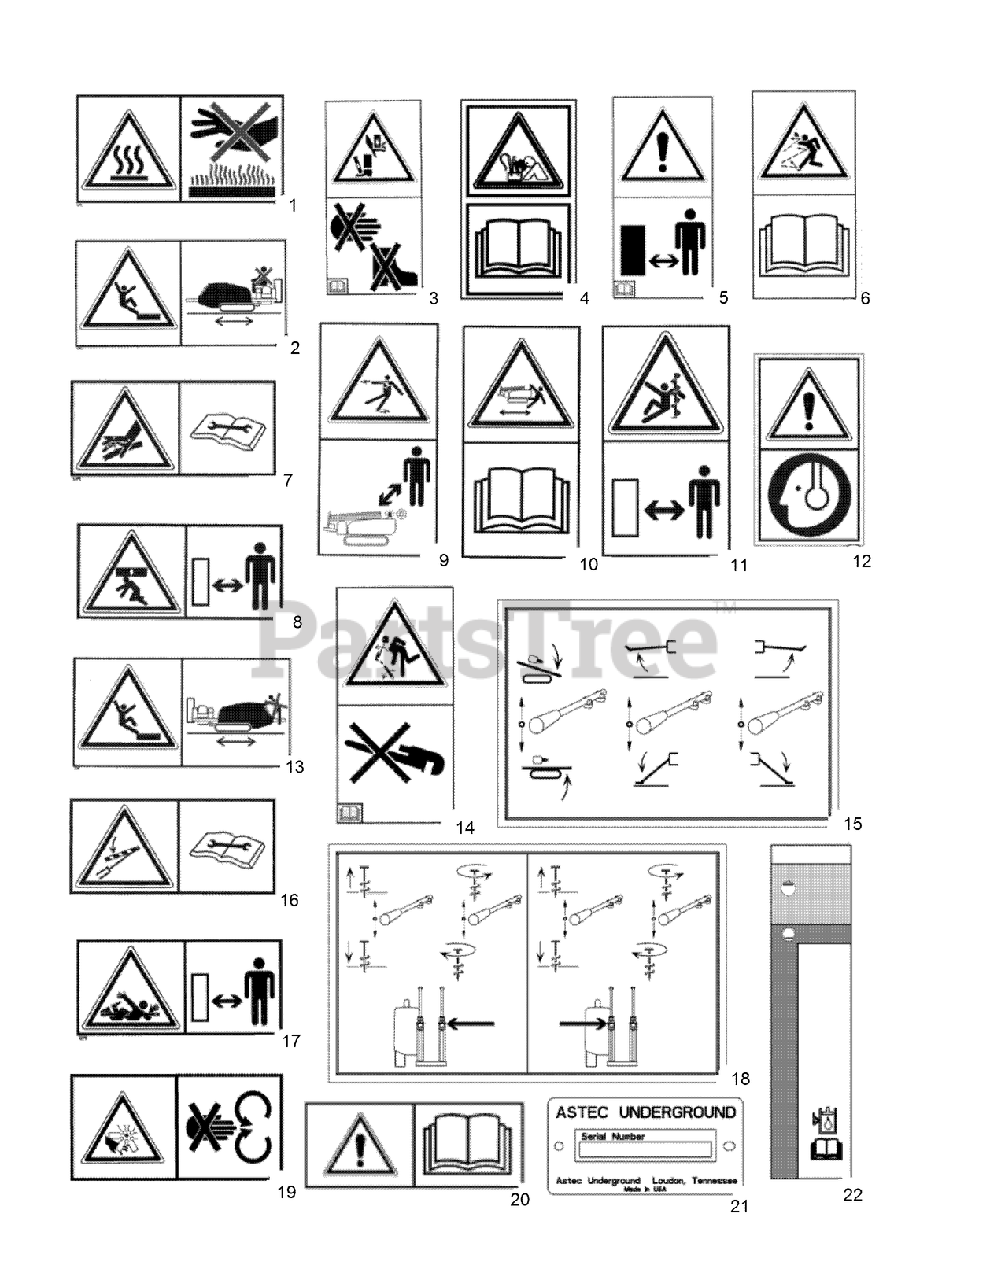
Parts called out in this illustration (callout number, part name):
1	DECAL-Hot Surface
2	DECAL - Warning, No Riders (Front), ISO
3	DECAL - Danger, Crush, Hands and Feet, ISO
4	DECAL-Battery Explosion
5	DECAL - Warning, Stand Clear, ISO
6	DECAL - Warning, Flying Objects, ISO
7	DECAL - Danger, Hydraulic Components Under Pressure, ISO
8	DECAL - Danger, Crush From Above, ISO
9	DECAL - Danger, Strike Alert Electrocution Hazard, ISO
10	DECAL - Danger, Runover Hazard, ISO
11	DECAL - Danger, Vertical Auger Entanglement, ISO
12	DECAL-Warning, Hearing Protection Required
13	DECAL - Warning, No Riders While Tramming, ISO
14	DECAL - Do Not Use Pipe Wrench, ISO
15	DECAL - Stabilizer/Thrust Frame Setup
16	DECAL - Warning, Use Cylinder Lock For Service, ISO
17	DECAL - Danger, Entanglement Hazard, Small, ISO
18	DECAL - Stakedown Setup
19	DECAL-Fan Entanglement
20	DECAL - Warning, Read Operators Manual, ISO
21	PLATE - Serial Number
22	DECAL-Hydraulic Oil Level
